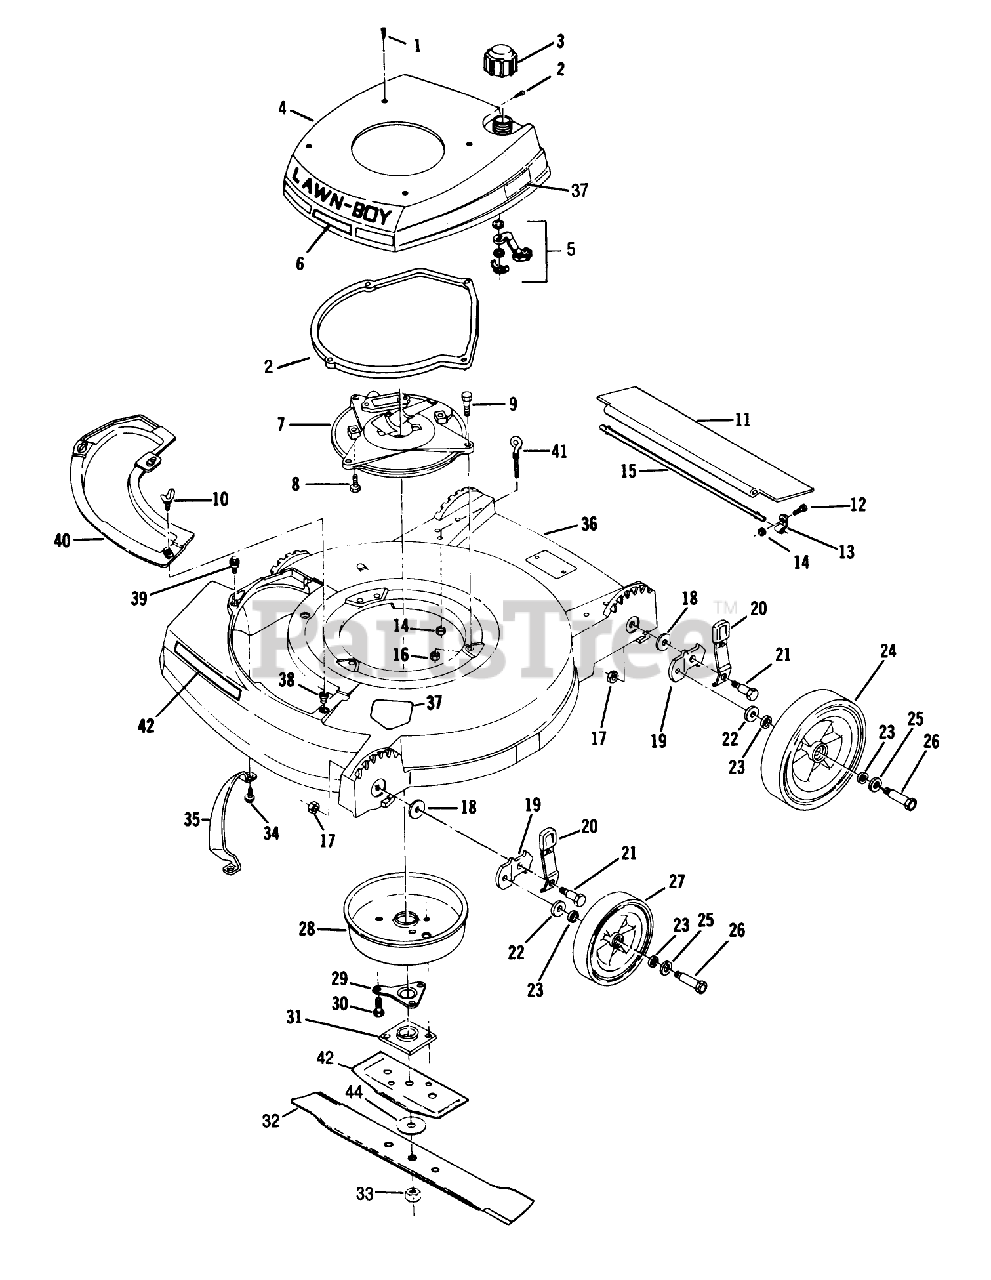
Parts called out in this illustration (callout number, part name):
1	SCREW S
3	FUEL CAP & INSERT
7	PLATE F
8	SCREW V
9	SCREW-HH
10	WING SCREW LAWRE
14	LOCKNUT E
15	ROD T/SHIELD ADV WIRE
16	NUT-LOCK F
17	LOCKNUT
18	WASHER
20	SPRING ARM ASM
21	BOLT
22	WASHER WROUGHT
23	WASHER
25	SPACER
26	BOLT WHEEL
27	WHEEL & TIRE KIT
28	MUFFLER COVER F
29	SUPPORT F
30	SCREW
31	PLATE AND COLLAR ASM
33	NUT-BLADE
35	TOE BAR 19"
41	BOLT-EYE
43	SCREW LAWRENCE
44	WASHER
